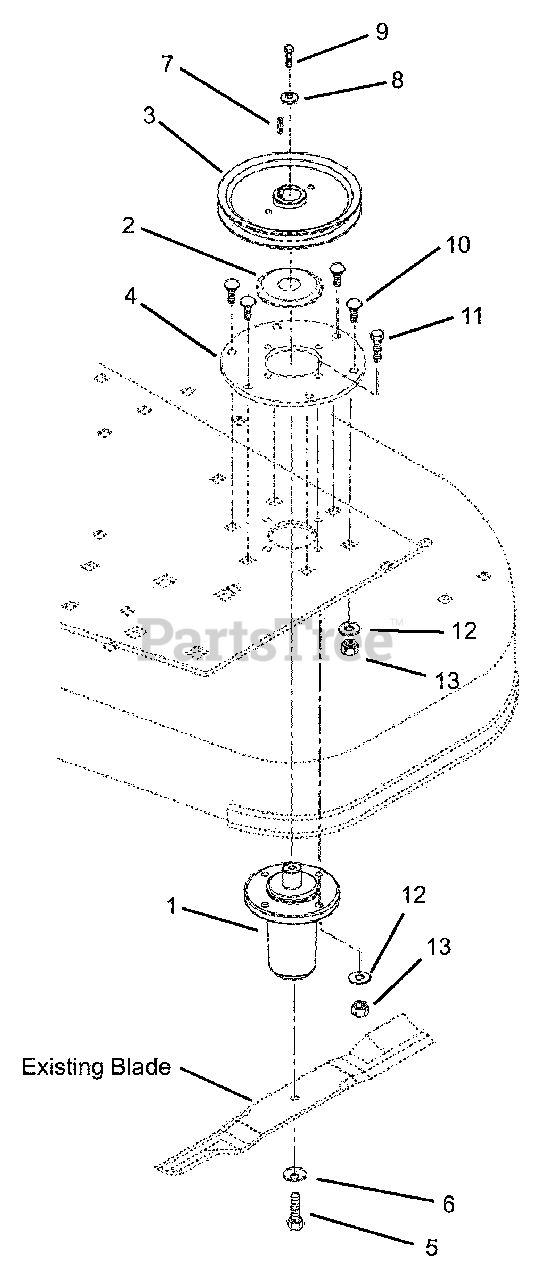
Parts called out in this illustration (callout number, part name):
1	Spindle Assembly
2	Dust Slinger
3	Sheave - 72" Deck
3	Sheave - 60" Deck
4	Reinforcing Plate
5	Bolt-Hex 5/8-18 x 1 3/4 Grade 8
6	Washer-Bevel
7	Key-Square
8	Washer-Flat 13/32 x 1 1/2
9	Bolt-Hex 3/8-16 x 1
10	Bolt-Round Head Square Neck 3/8-16 x 1 1/4
11	Bolt-Hex 3/8-16 x 1 3/4
12	Washer-Flat 13/32 x 13/16
13	Nut-Locking Nyl 3/8-16
